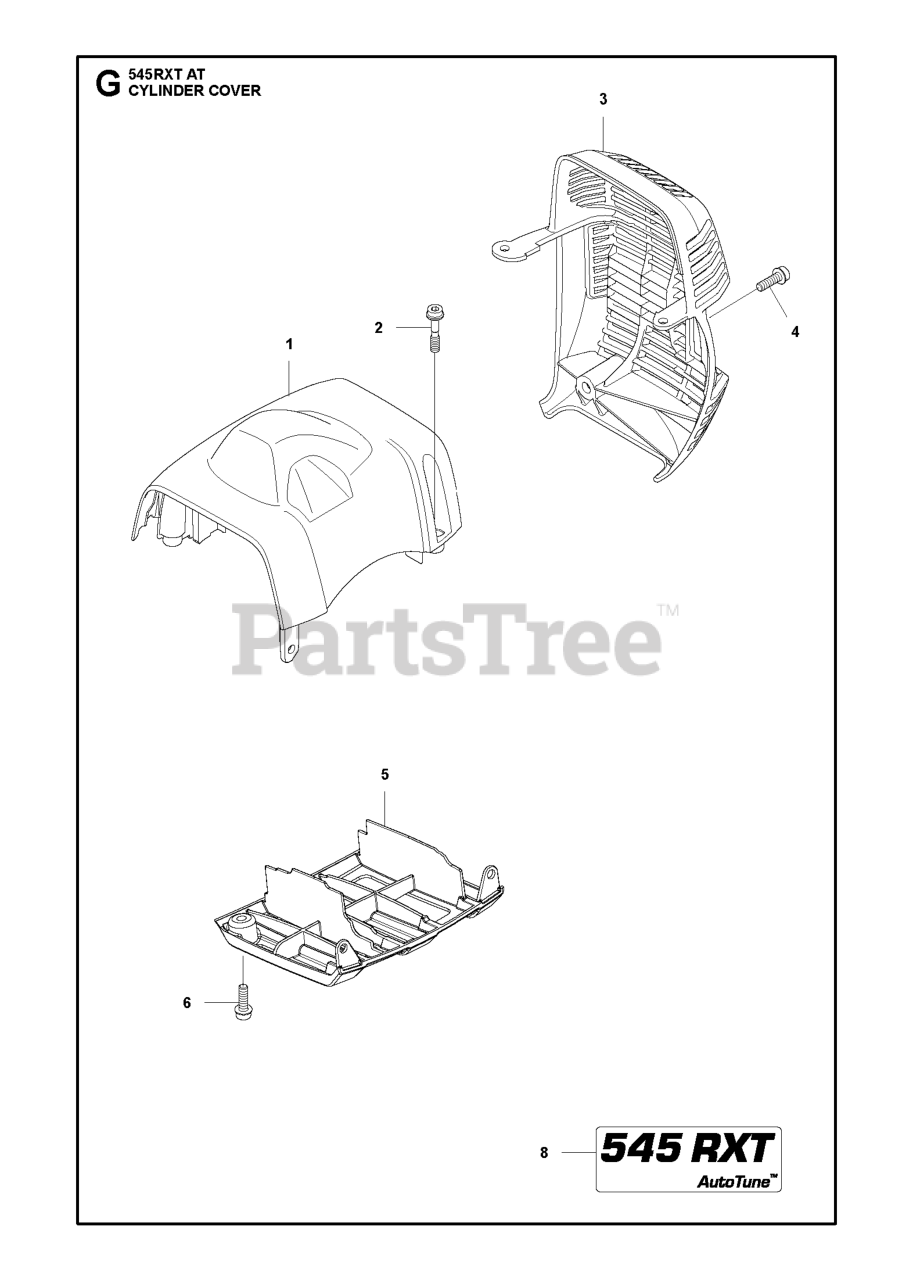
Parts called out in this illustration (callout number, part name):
1	CYLINDER COVER
2	SCREW IHSCFMO
3	HEAT PROTECTOR
4	SCREW IHSCFM
5	PROTECTIVE COVER
6	SCREW IHSCFM
8	LABEL CYLINDER COVER RXT
